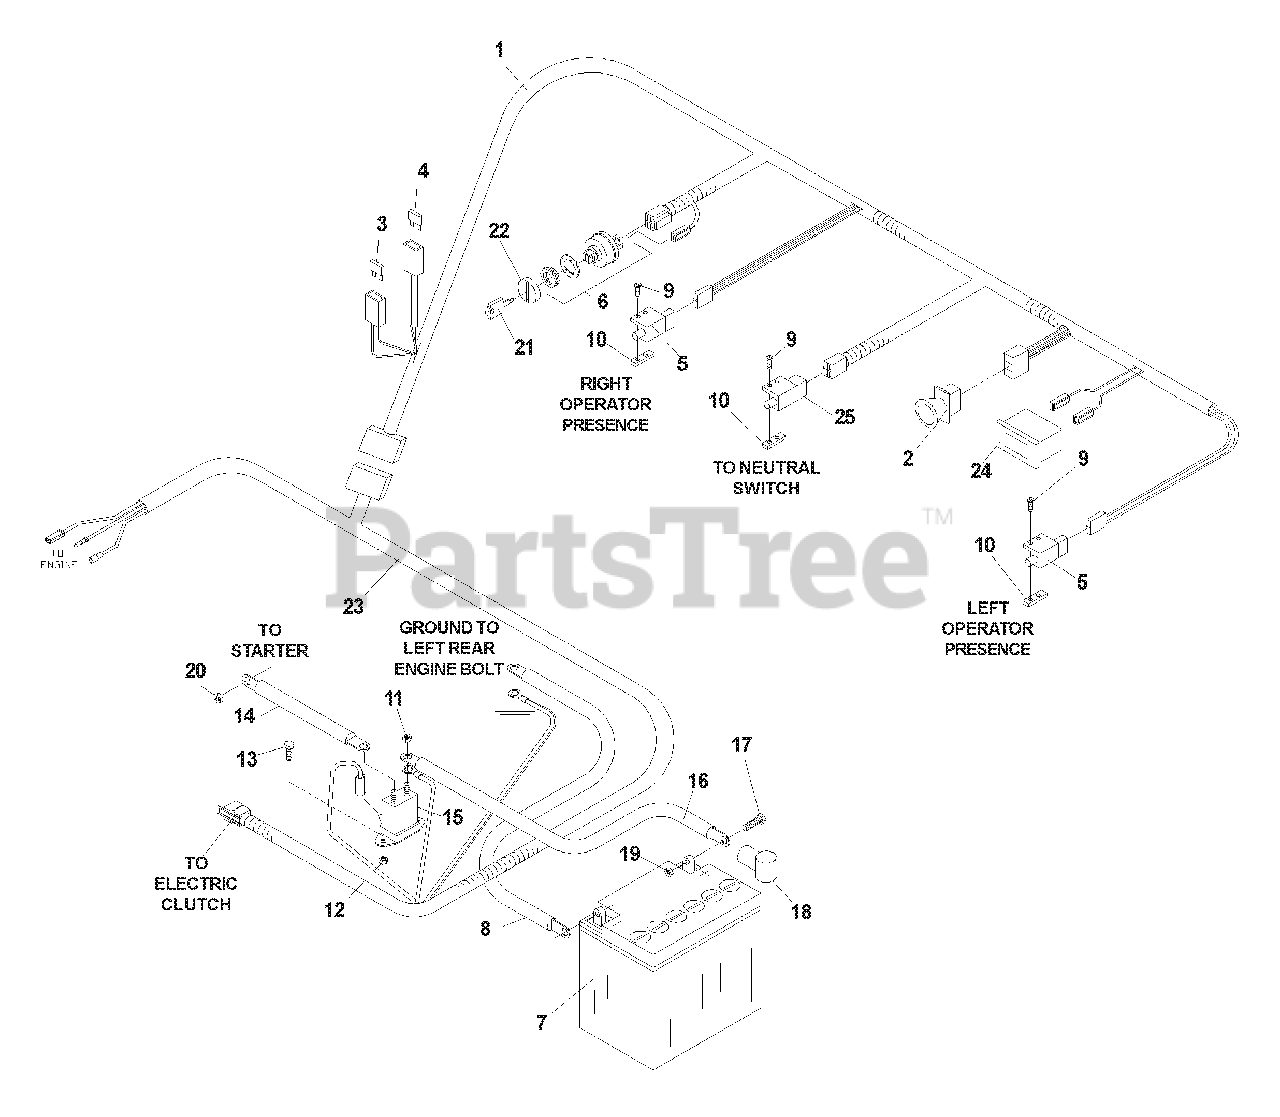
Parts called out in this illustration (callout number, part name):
1	UPPER HARNESS
2	CLUTCH SWITCH
3	FUSE 20 AMP
4	FUSE 7.5 AMP
5	SWITCH N. C.
6	IGNITION SWITCH
6	NUT, SWITCH
7	BATTERY
8	NEG. CABLE
9	SCREW #10-24
10	TAPPED PLATE
11	NUT 1/4
12	NUT 1/4 LOCK
13	HCS 1/4 X .625
14	POS. CABLE
16	POS. CABLE LONG
17	HCS 5/16 X .750
19	NUT 5/16 CTR. LOCK
20	NUT 1/4 THIN NYLOC
23	LOWER HARNESSS
24	HOUR METER
25	2 POLE SWITCH
